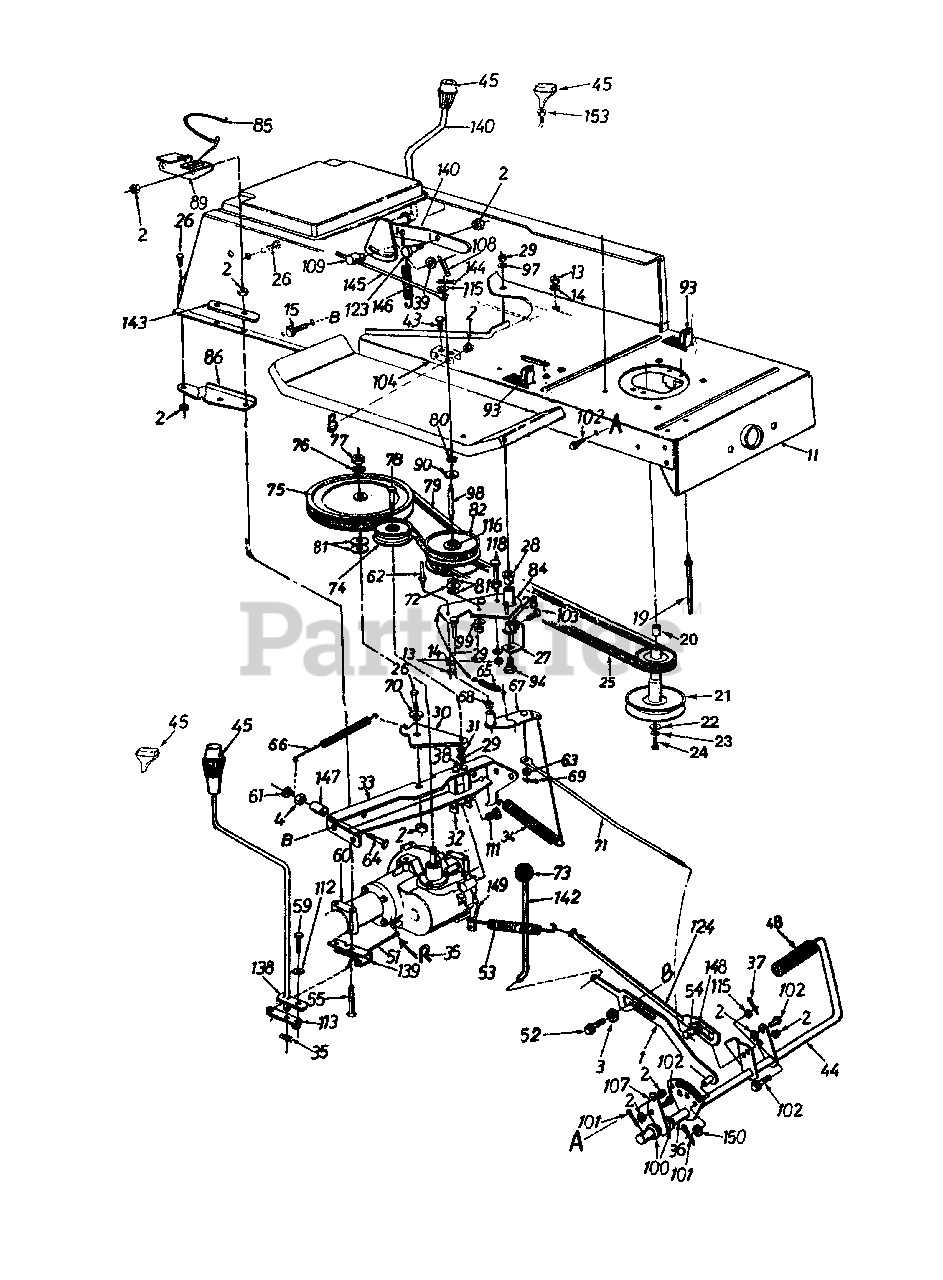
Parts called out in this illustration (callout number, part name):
1	Parking Brake Lockout Brkt. Ass'y.
2	Hex Sems Nut 5/16-18 Thd.
3	Fl-Wash. .442" I.D. x 1.38" O.D.
4	Hex Nut 5/16-24 Thd.
13	Hex Nut 1/4-20Thd.
14	L-Wash. 1/4" I.D.
15	Hex TT-Tap Scr. 5/16-18 x .62"
19	Belt Guard Pin
20	Spacer 1" I.D.
21	Engine Pulley
22	Shld. Spacer .445" I.D.
23	L-Wash. 7/16" I.D.
24	Hex Bolt 7/16-20 x 1 1/4" Lg.
25	Variable Speed Belt
26	Hex Bolt 5/16-18 x .75" Lg.
27	Bearing Shaft Bracket Ass'y.
28	Flanged Nyliner Brg. .63" 1.D. x .6" Lg.
29	Hex Nut 3/8-24 Thd.
30	Idler Bracket
31	L-Wash. 3/8" I.D.
35	Inter. Cotter Pin
36	Spacer .63" I.D.
37	Cotter Pin 1/8" Dia. x 1.0" Lg.
38	Self-Tap Scr. 5/16-18 x .5" Lg.
39	FL-Wash. .51" I.D. x .75"
43	Hex Wash. Hd. S-Tap Scr. 1/4-20 x .50" Lg.
48	Foot Pad
51	Shift Lever Rod
52	Shld. Bolt .437"
53	Ext. Spring 3.6"
54	Ferrule
55	Hex Bolt 5/16-18 x 3.25"
59	Hex Bolt 1/4-28 x .62" Lg.
60	Transaxle Complete
61	Hex L-Nut 1/4-20 Thd.
62	Belt Guard Pin 1/4-20 Thd.
63	Fl-Wash. .34" I.D. x .68" O.D.
64	Hex Wash. TT-Tap Scr. 1/4-20 x 1.75"
65	Ext. Spring 2.59" Lg.
66	Ext. Spring .5" O.D. x 4.35"
68	Flanged Bearing
69	Cotter Pin 3/32" Dia.
70	Shoulder Spacer .27" Lg.
71	Speed Control Link
72	Truss Bearing .56 Dia. x 1.25"
73	Ball Knob
74	Fl-Idler Pulley 3.25" x .75"
75	"V"-Pulley
76	L-Wash. 1/2" I.D.
77	Hex Jam Nut 1/2-20 Thd.
78	Hex Bolt 3/8-24 x 1.75" Lg.
79	Variable Speed Belt
80	Snap Ring .56" Dia.
81	Fl-Wash. .56" I.D. x 1.0" O.D.
82	Variable Speed Pulley Ass'y. 5" O.D.
90	Teflon Washer .565" I.D.
93	Safety Switch (Clutch)
94	Shld. Bolt 3/8-24 x 3.12" Lg.
97	Bell-Wash. .38" I.D. x .88"
98	Shaft
99	Bell-Wash. .39" I.D. x 1.12"
100	Fl-Wash. .64" I.D. x .94"
101	Cotter Pin 3/32" Dia. x 1" Lg.
102	Hex Wash. Hd. Scr. 5/16-18 x .62" Lg.
103	Hex Wash. Hd. AB-Tap Scr. .75" Lg.
104	Bracket
109	Ferrule
111	Hex Wash. Tap Scr.
112	Bell-Wash. .265" I.D. x .75"
113	Shift Lever Link Ass'y.
115	Fl-Wash. .385" I.D. x .62"
116	Needle Brgs.
118	Hex Bolt 1/4-20 x 3.5" Lg.
123	Shld. Bolt .437" Dia. x .162"
124	Brake Rod Ass'y.
138	Shift Lever Ass'y.
139	Shift Lever Support Brkt.
140	Speed Selector Lever Ass'y.
142	Brake Lockout Rod
144	Cotter Pin 1/8" x 3/4" Lg.
145	Speed Selector Rod
146	Ext. Spring 3.97" Lg.
147	Spacer .326" I.D. x .47"
148	Fl-Wash. 5/8" I.D. x 1.25"
149	Actuating Arm
150	Fl-Wash. .385" I.D. x .62" O.D.
153	Hex Jam Nut 3/8-16 Thd.
